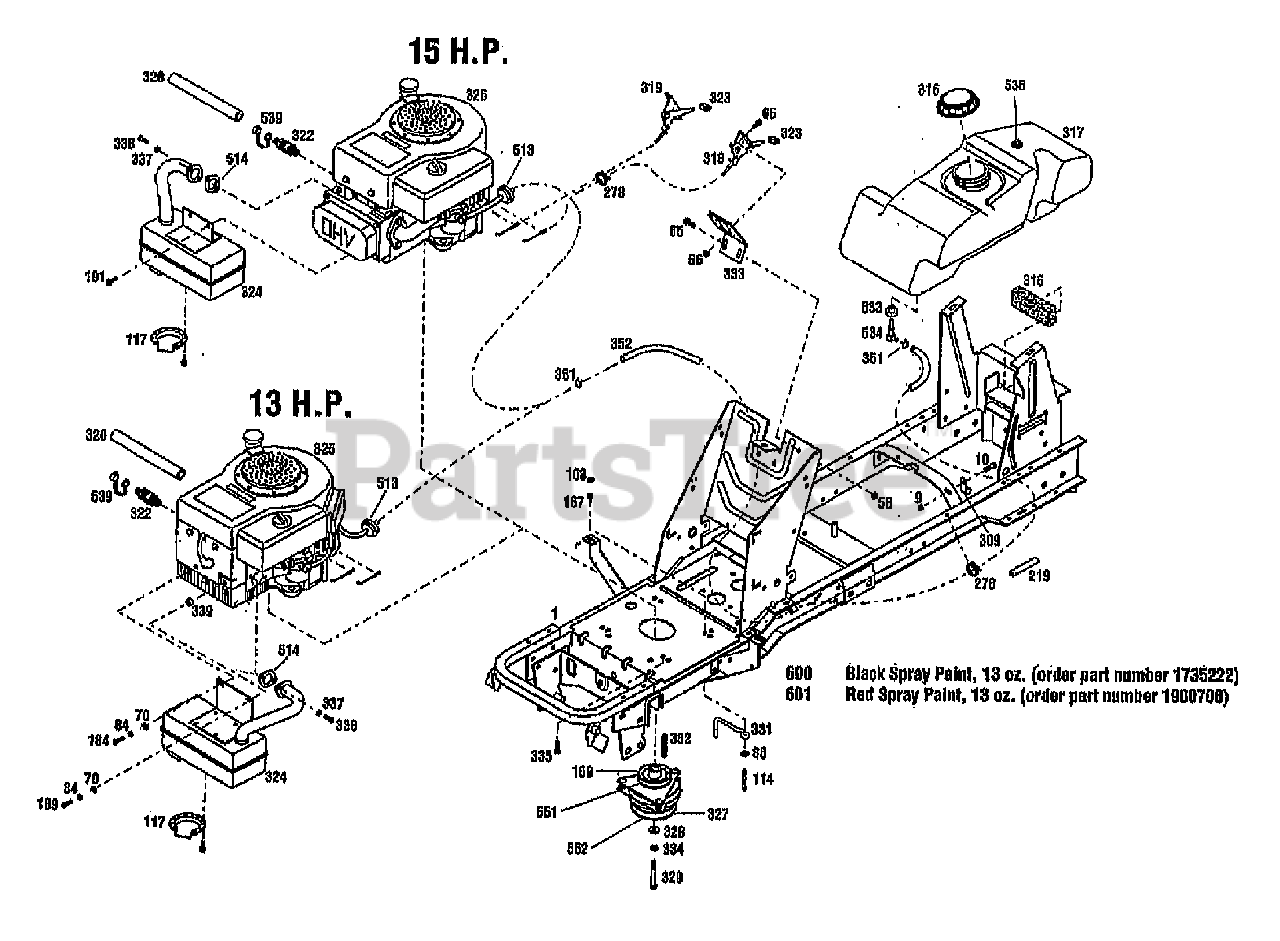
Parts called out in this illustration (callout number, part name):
1	ASSM-FRAME LTX
9	NUT-HFLK 5/16-18 ZP
10	SCR-HHC 5/16-18X.75 GR 5 ZP
56	NUT-HF/LK 1/4-20 ZP
65	SCR-HH 1/4-20X.625
70	WASHER-FLAT 1/4 SAE
84	WASHER-LK .25 ZP
114	SCR-THRD FRM 3/8-16X1.50
117	DEFLECTOR-MUFFLER
163	NUT-HEX 3/8-16 ZP
167	WASHER-LK .375 @ DEPL
184	SCR-HH 1/4-20 X .875
189	SCR-HH 1/4-20X1.25
191	SCR-FLANGE 1/4-20X3/4 GR5
278	TIE-CABLE NYLON BLACK
309	CLIP-J
316	CAP-FUEL
317	TANK-FUEL
318	CONTROL-THROTTLE
319	CONTROL-CHOKE
320	HOSE-OIL DRAIN
322	ASSM-OIL VALVE
324	MUFFLER
325	ENGINE, 13HP BRIGGS & STRATTON, MODEL 28M707
325	ENGINE, 15HP BRIGGS & STRATTON, MODEL 28N707
327	CLUTCH-ELECTRIC
329	SCR-HH 7/16-20X3.00
331	CLUTCH-RETAINER
332	KEY-.25 SQ X 2.5
333	BRKT-MOUNTING CONTROL
334	WASHER-LK .438 ZP
335	SCR-HH 3/8-16X1.0 THDFM
337	WASHER-LOCK
338	SCR-HXSKT 5/16-18X.75 BO
339	SPACER-.625X.344X.34
351	CLAMP-HOSE
352	LINE-FUEL
513	FILTER-FUEL
514	MUFFLER GASKET
533	BUSHING-RUBBER
534	ELBOW-90 DEG (FUEL LINE)
539	CAP-OIL DRAIN
551	BEARING-UPPER CLUTCH
600	PAINT-BLACK SPRAY
601	PAINT-RED SPRAYCAN POWDER
